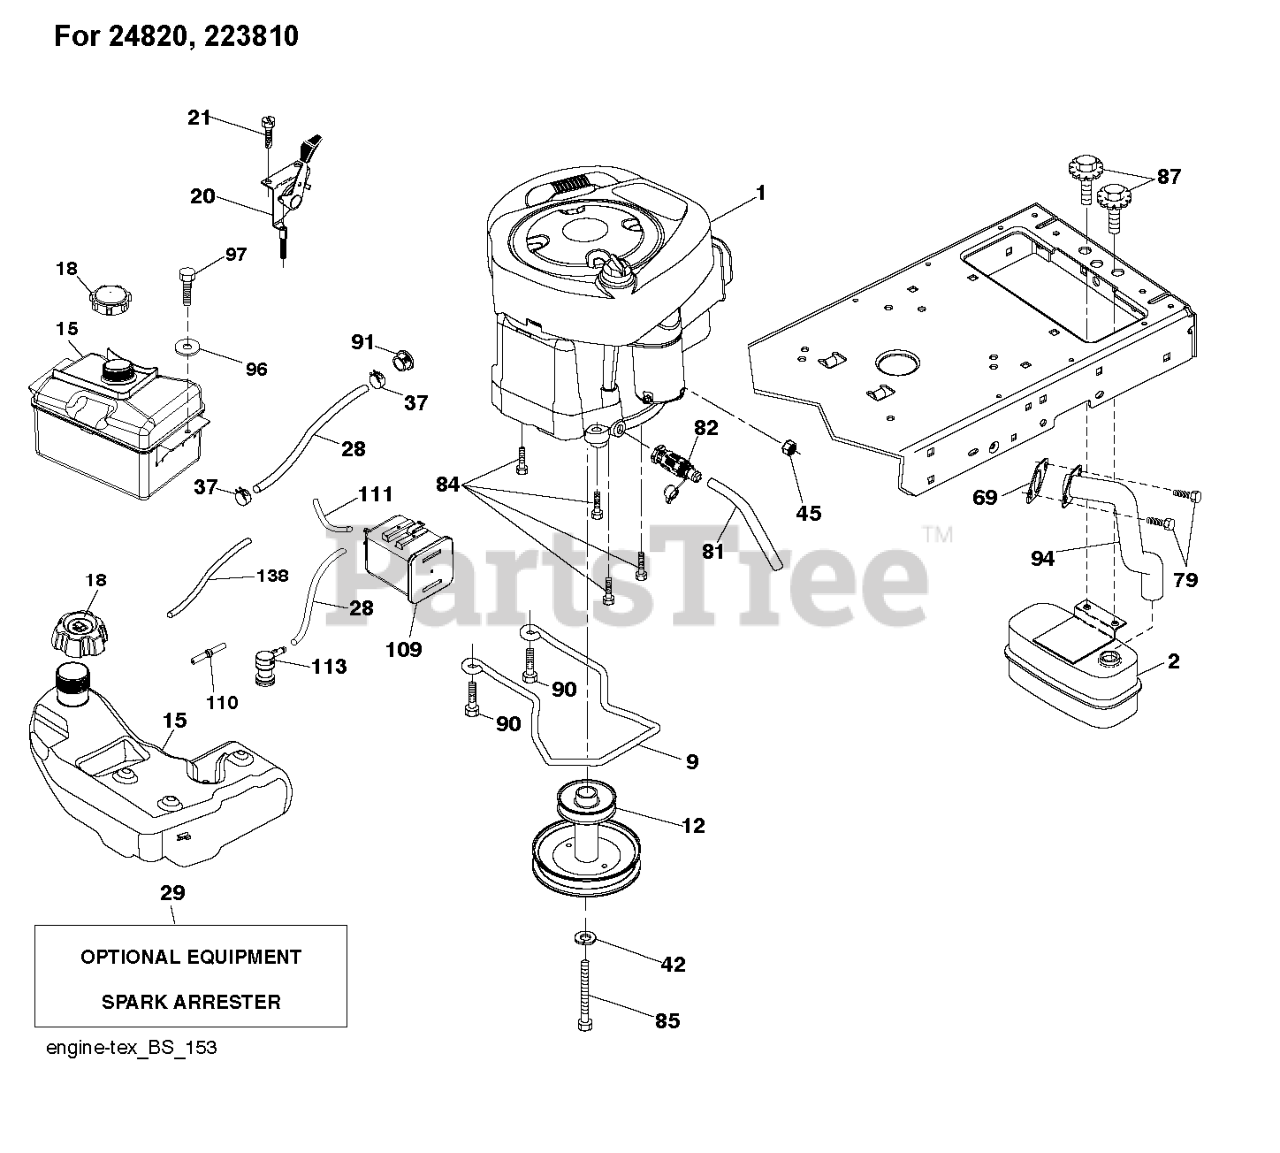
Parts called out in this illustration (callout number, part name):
2	MUFFLER.ASM.SINGLE
9	KEEPER.BELT.ENG.4.25"2.BLT.431
12	ENGINE.PULLEY
15	FUEL TANKS
15	FUEL TANK
18	CAP.FUEL.2 WAY VENT
18	Fuel Caps
18	FUEL CAP
20	CONTROL.TH/CK.C.
28	LINE.FUEL.64"REAR.EMIS
29	KIT.SPARK ARRESTOR 794945 B&S
37	HOSE CLAMP
69	REPL BY 532 27 22-93
81	TUBE, DRAIN OIL ASM.
82	VALUE.OIL.DRAIN
84	SCREW.3/8-16
85	BOLT.HEX.7/16-20X4.GR5.1.5BLUE
87	BOLT.5/16-18UNCX3/4 W/SEMS.BLK
90	SCREW 3/8-16X1
91	BUSHING.1.375OD
94	EXHAUST.TUBE.B&S.28/31
96	Washers
97	SCREW HEXWSHR 1/4-20X3/4
109	CANNISTER, CARBON
110	VALVE.ASM.ANTI-SLOSH
111	TUBE.PURGE.FUEL.1875
113	VALVE.SLANT.CARTRDG.90 DEG.TEX
138	TUBE.PURGE.FUEL.1875
